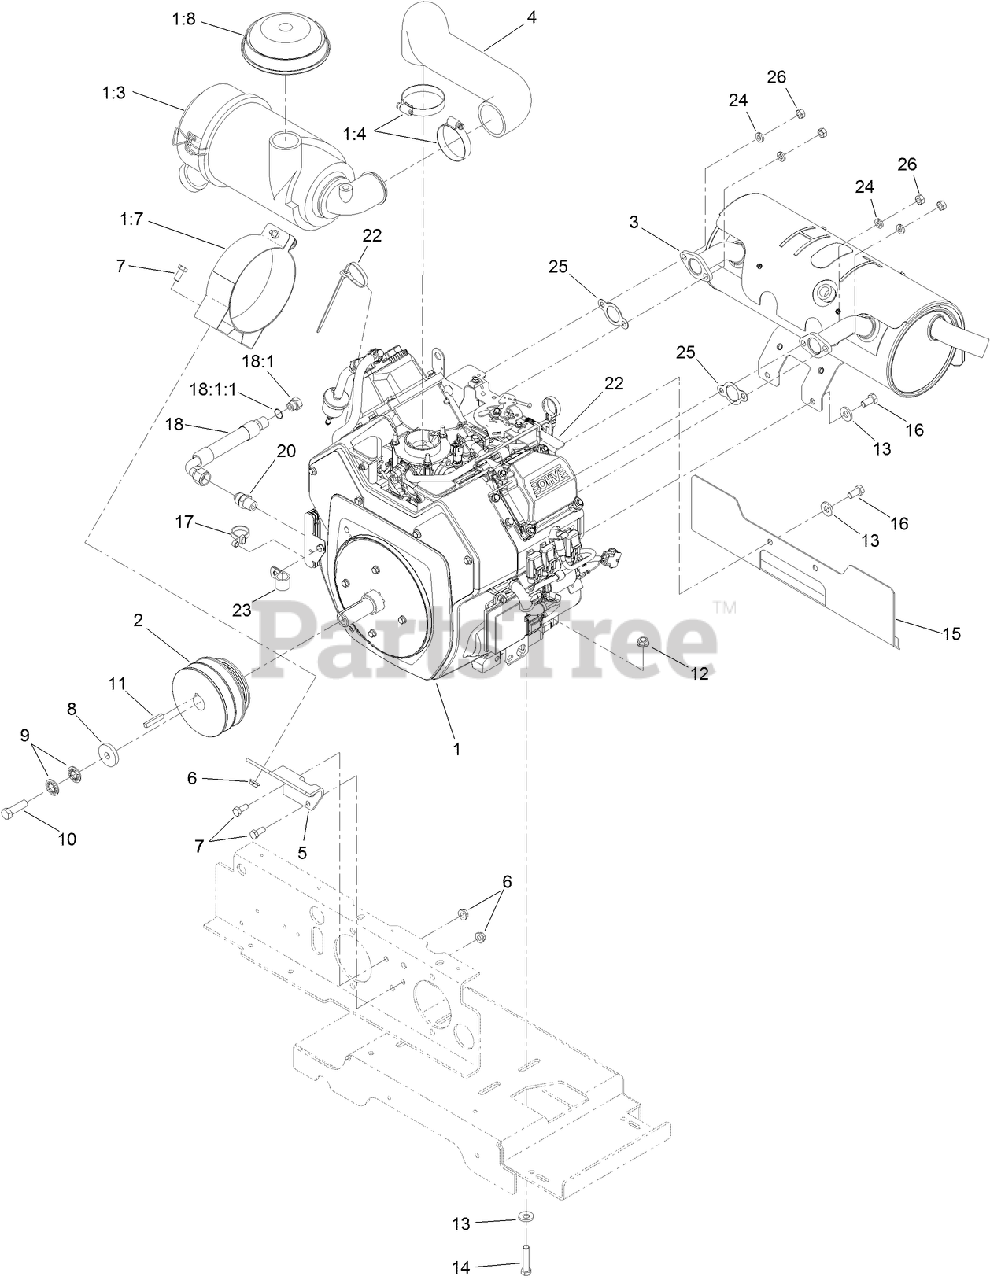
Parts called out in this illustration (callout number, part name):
1:3	AIR CLEANER CANISTER ASM
1:4	CLAMP-HOSE
1:7	BRACKET-FILTER, AIR
1:8	HOOD-CLEANER, 2" AIR INTAKE
2	SHEAVE-ENGINE
3	Muffler
4	HOSE-AIR INTAKE
5	BRACKET-FILTER, AIR
6	NUT-HF
7	SCREW-HH
8	WASHER-CLUTCH
9	WASHER-SPRING
10	SCREW-HH
11	KEY-SQUARE
12	NUT-HHF, WHIZ
13	WASHER-BELLEVILLE
14	SCREW-HH
15	SHIELD-EXHAUST
16	SCREW-HH
17	TIE-CABLE
18	OIL DRAIN HOSE ASM
18:1	PLUG-HH
18:1:1	O-RING
20	FITTING-STRAIGHT
22	TIE-PLASTIC
23	CLIP-LOOM
24	WASHER-LOCK
25	GASKET-EXHAUST
26	NUT-HEX
